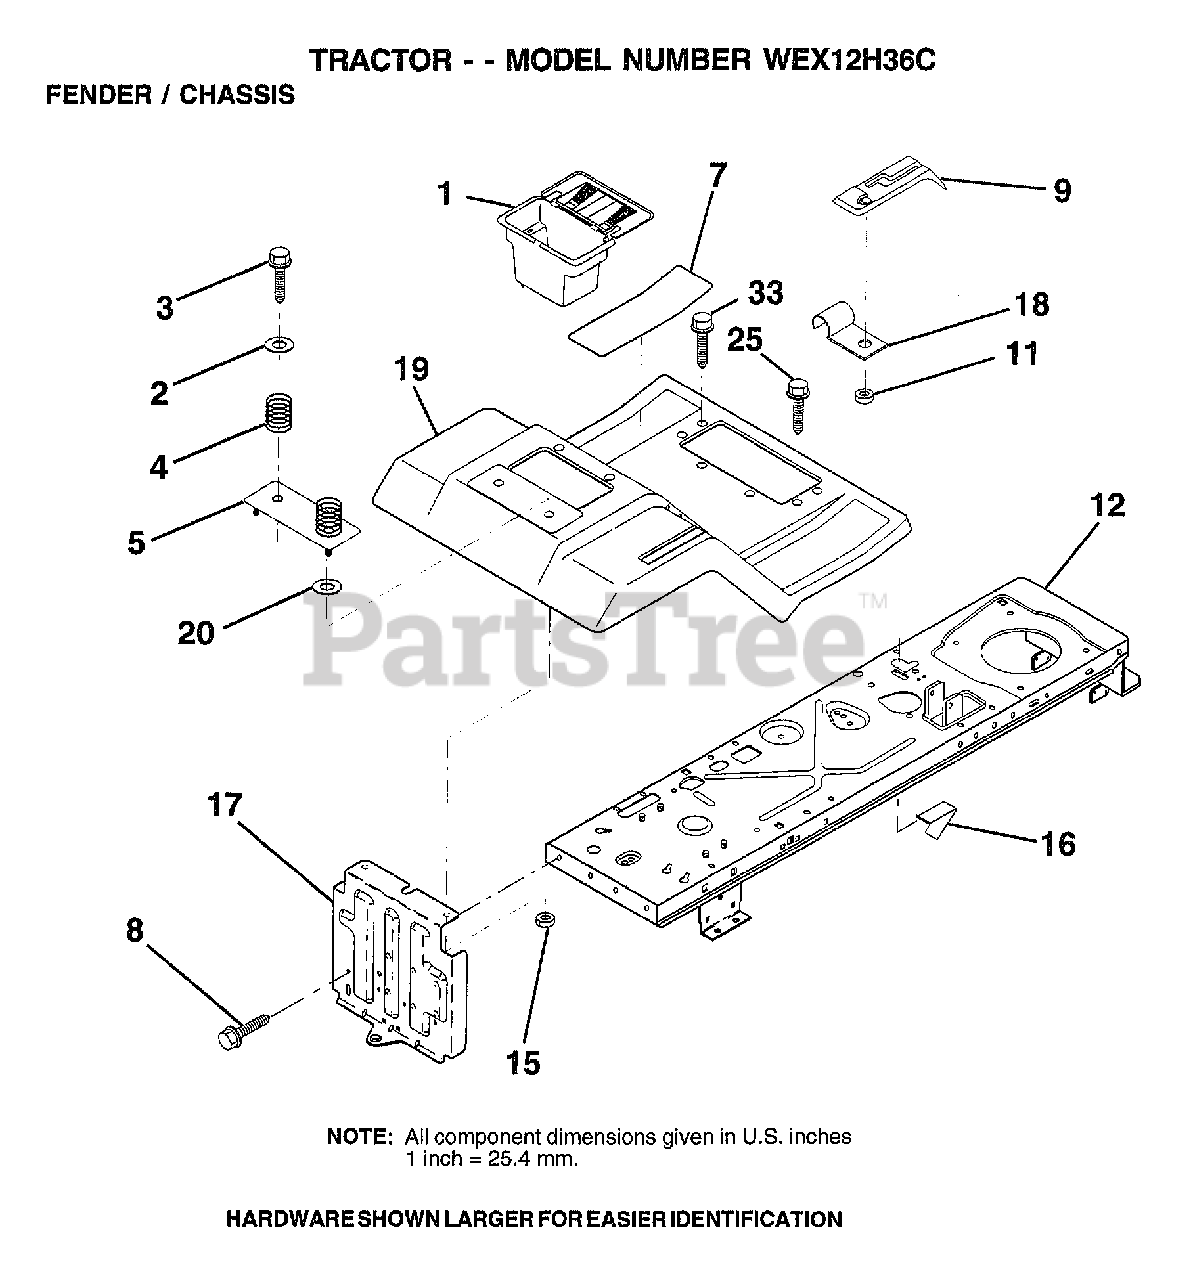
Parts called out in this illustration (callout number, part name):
1	"CASE,BATTERY.MECH"
2	WASHER
3	SCREW
4	SPRING COMPRESSIO
5	PLATE.FEND.LR.ASM
7	PAD FOOTREST
8	SCREW
9	CONSOLE.SHIFT CONTROL
11	NUT
12	CHASSIS.WELD.ASM.
15	NUT HXKEP 1/4X20
17	DRAWBAR ASM LR
18	"CLIP,INSULATOR"
19	FENDER/FOOTREST
25	SCREW TAPPING
33	SCREW
